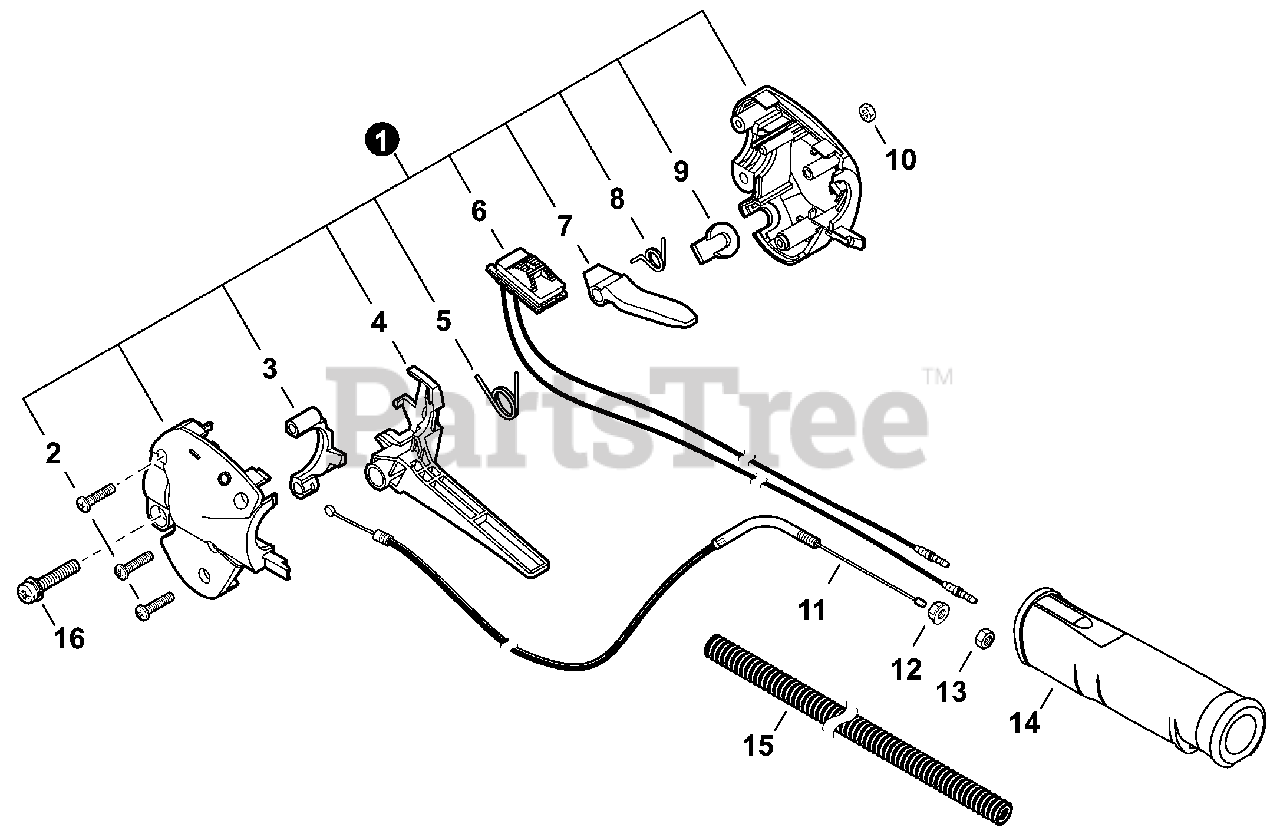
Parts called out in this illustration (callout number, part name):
1	THROTTLE CONTROL ASSY
3	LOCKOUT, THROTTLE
4	TRIGGER, THROTTLE
5	SPRING, THROTTLE RETURN
6	SWITCH, ON-OFF
7	LEVER, THROTTLE LOCKOUT
8	SPRING, THROTTLE LOCKOUT
11	CABLE, THROTTLE
12	NUT, FLANGE M6
14	GRIP, HANDLE
15	TUBE, PLASTIC PROTECTIVE
16	BOLT, TORX 5x16
